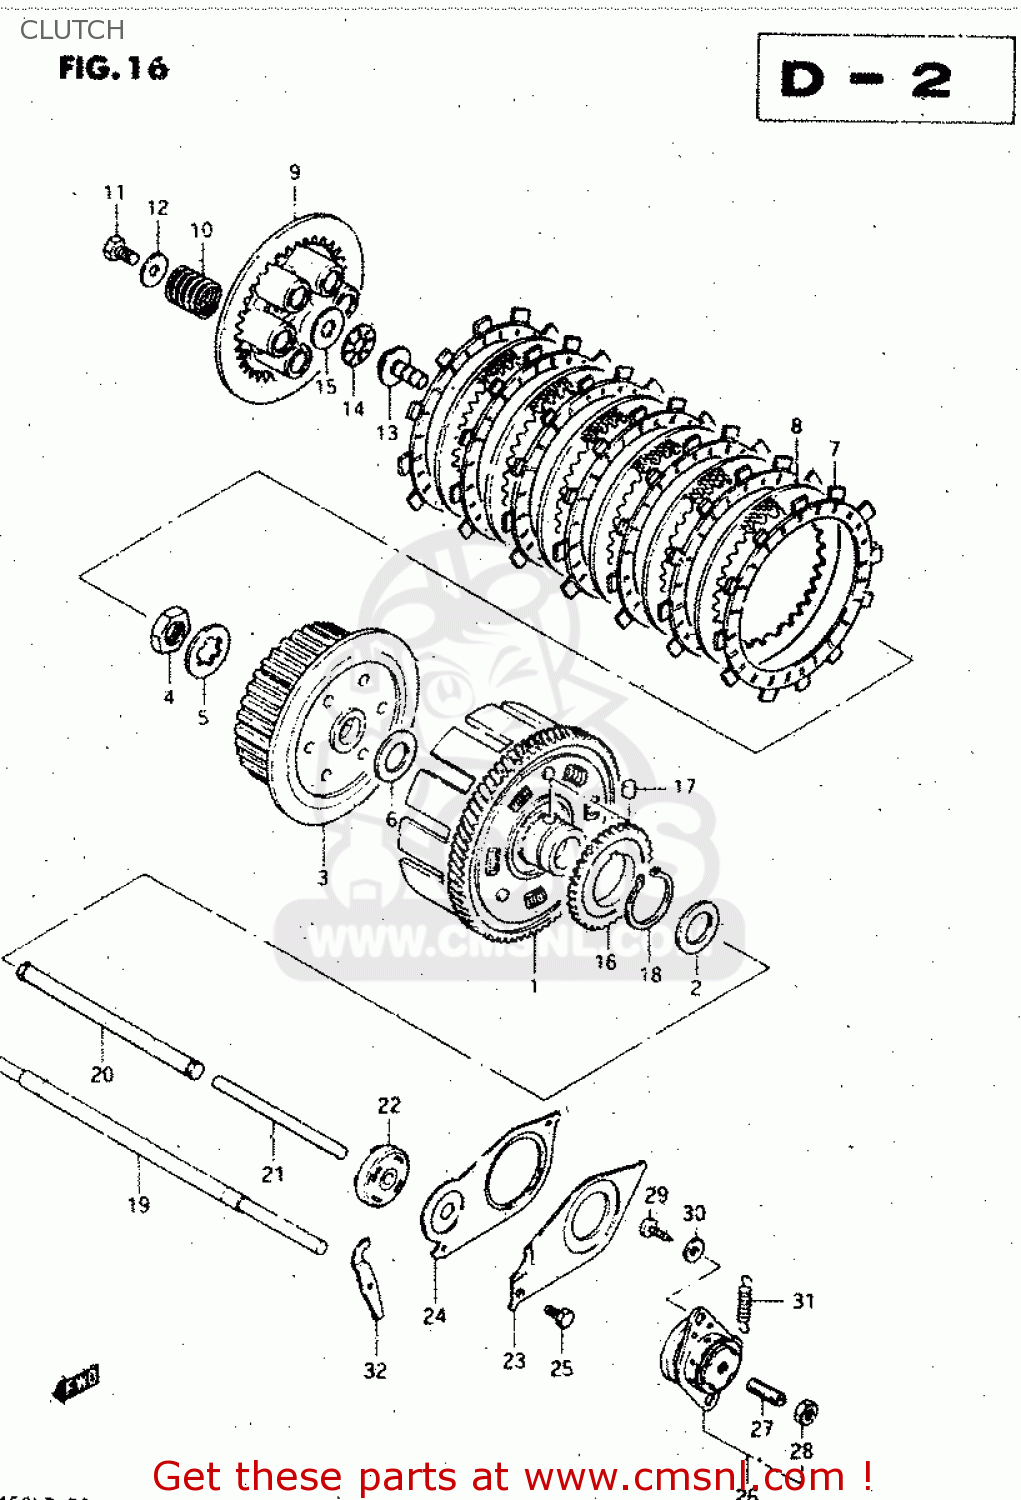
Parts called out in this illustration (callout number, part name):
1	GEAR ASSEMBLY,PRIMARY DRIVE
2	WASHER
3	HUB,CLUTCH SLEEVE
4	NUT (20MM)
5	WASHER,LOCK
6	WASHER(20X44X3)
7	PLATE,CLUTCH DRIVE (MCA)
8	PLATE,CLUTCH DRIVEN (NAS)
9	DISC,CLUTCH PRESSURE
10	SPRING
11	BOLT, UPPER
12	WASHER
13	PIECE,CLUTCH PUSH
14	BEARING(15X28X2)
15	WASHER
16	GEAR,OIL PUMP DRIVE
17	PIN(6X6)
18	CIRCLIP
19	ROD,CLUTCH PUSH
20	ROD,CLUTCH PUSH
21	ROD,CLUTCH PUSH
22	SEAL,OIL(6X34X8)
23	PLATE,CLUTCH PUSH ROD
24	PLATE,CLUTCH PUSH ROD
25	BOLT
26	SCREW ASSY,CLUTCH RELEASE
27	SCREW
28	NUT 6MM
29	SCREW
30	WASHER
31	SPRING
32	GUIDE,PUSH ROD OIL SEAL
